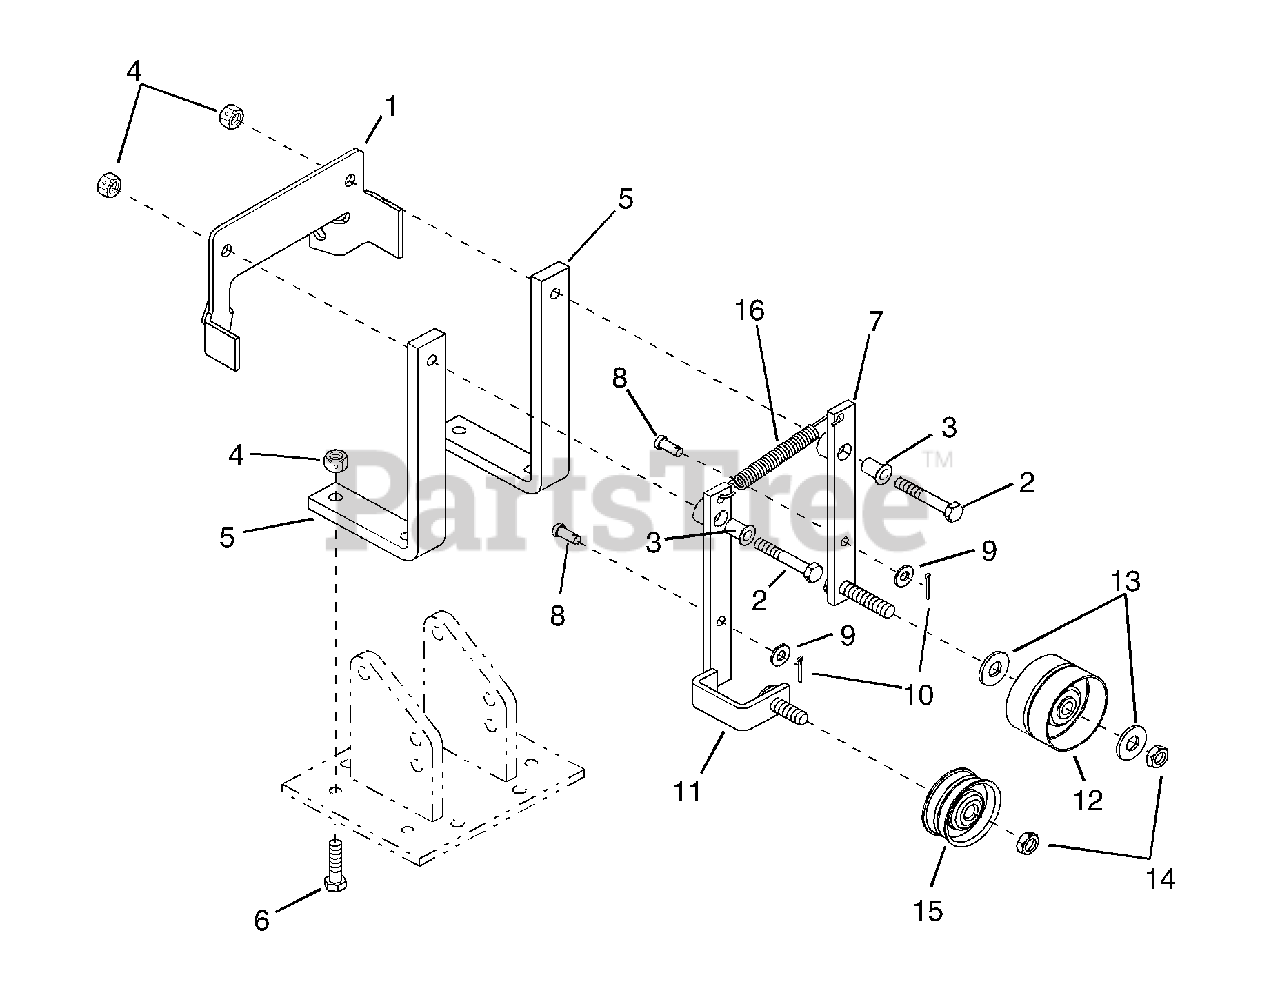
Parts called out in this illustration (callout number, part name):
1	PLATE, ANCHOR
2	@BLT-HEX .31-18X2.00 GR5 YWZC
3	BSHG-FLG .325X.465X.831X.685
4	@NUT-LK-CTR .31-18 YWZC
5	SHIFT MOUNTING BAR
6	@BLT-HEX .31-18X1.25 GR5 YWZC
7	IDLER ARM - FORWARD
8	PIN-CLEV .25X.62
9	@WSHR-FL-STL.281X.62X.065 YWZC
10	@PIN-CTR .06X.50 EXTPRSQCT YWZ
11	IDLER ARM - REVERSE
12	IDLER-FLAT 2.25 X .38
13	@WSHR-FL-STL.438X1.00X.083 YWZ
14	@NUT-LK-CTR-JAM .375-16 YWZC
15	IDLER-FLAT 2.000X.375
16	SG-TENS .047X.44X3.5 WLD 3
